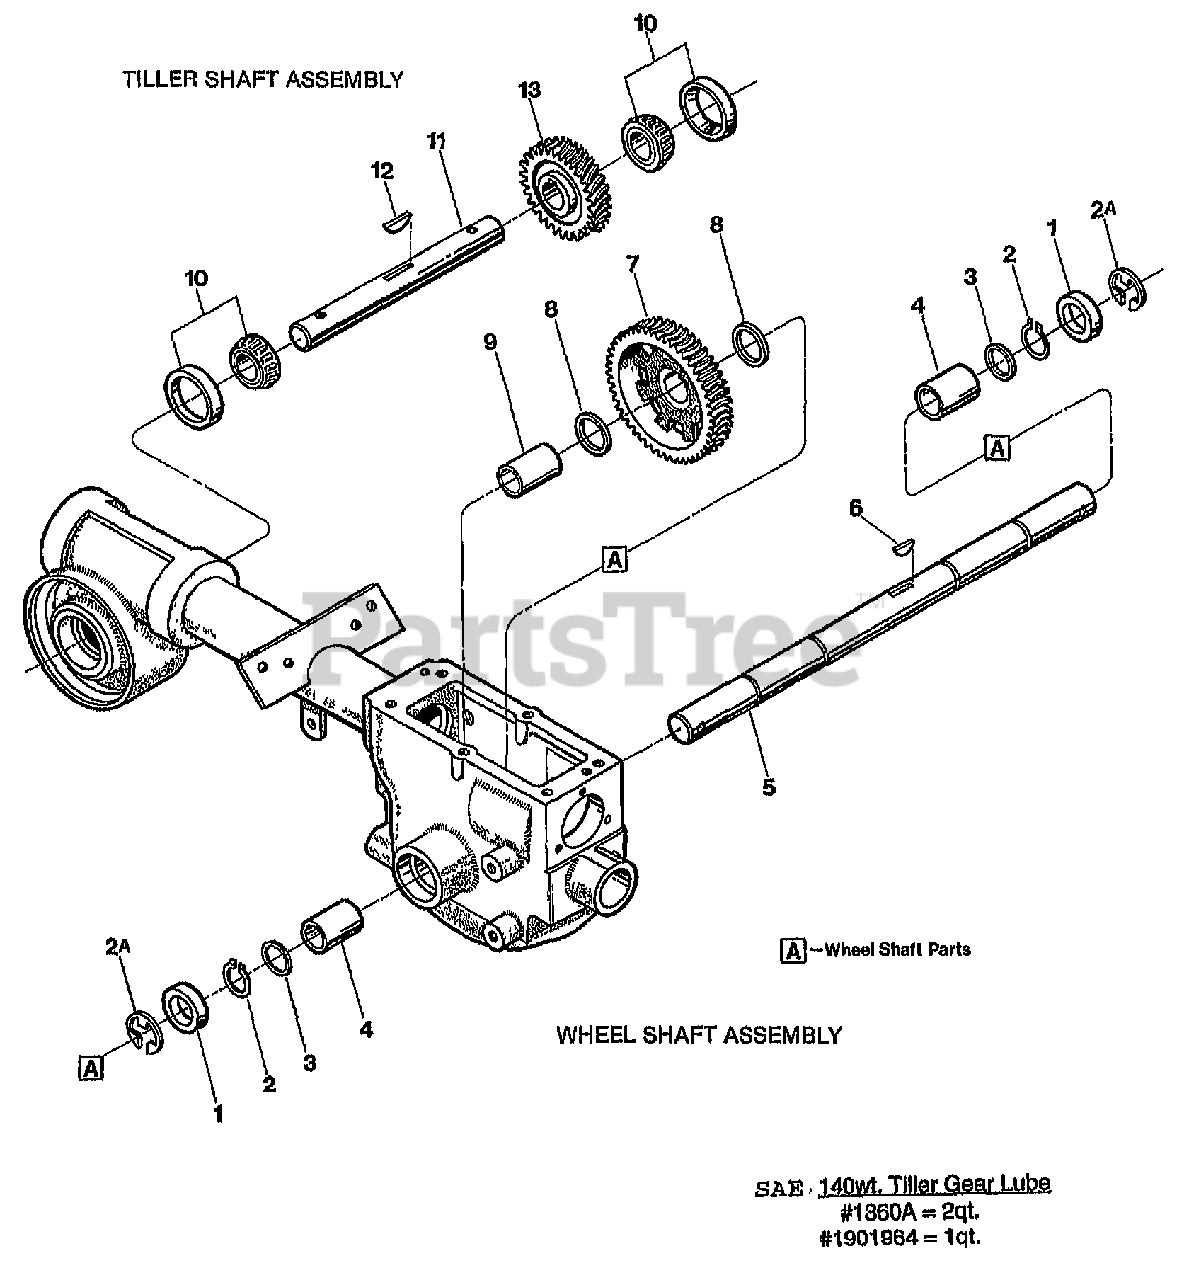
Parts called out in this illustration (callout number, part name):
1	SEAL-OIL WHEELSHAFT (LT & RT SIDES)
2	RING-HEAVY EXT .906 ID
2A	RING-RETAINING 5133-989
3	SHIM-1.375X1.015X.062
3	SHIM-1.375X1.015X.03
3	SHIM-1.375X1.015X.015
3	SHIM-1.375X1.015X.01
4	BUSHING-1.25X1.005X1.5
5	ASSM-WHEELSHAFT (INCL KEY #9097)
6	KEY-HI PRO .25X.938
7	GEAR-MACH
8	SHIM-1.234X1.015X.01
9	SPACER-WHEEL SHAFT
10	BEARING CUP & CONE (W/ RACE)
11	SHAFT W/KEY (TILLER)
12	KEY-WOODRUFF .25X1.12
13	GEAR-TILLER MACH (BRONZE)
